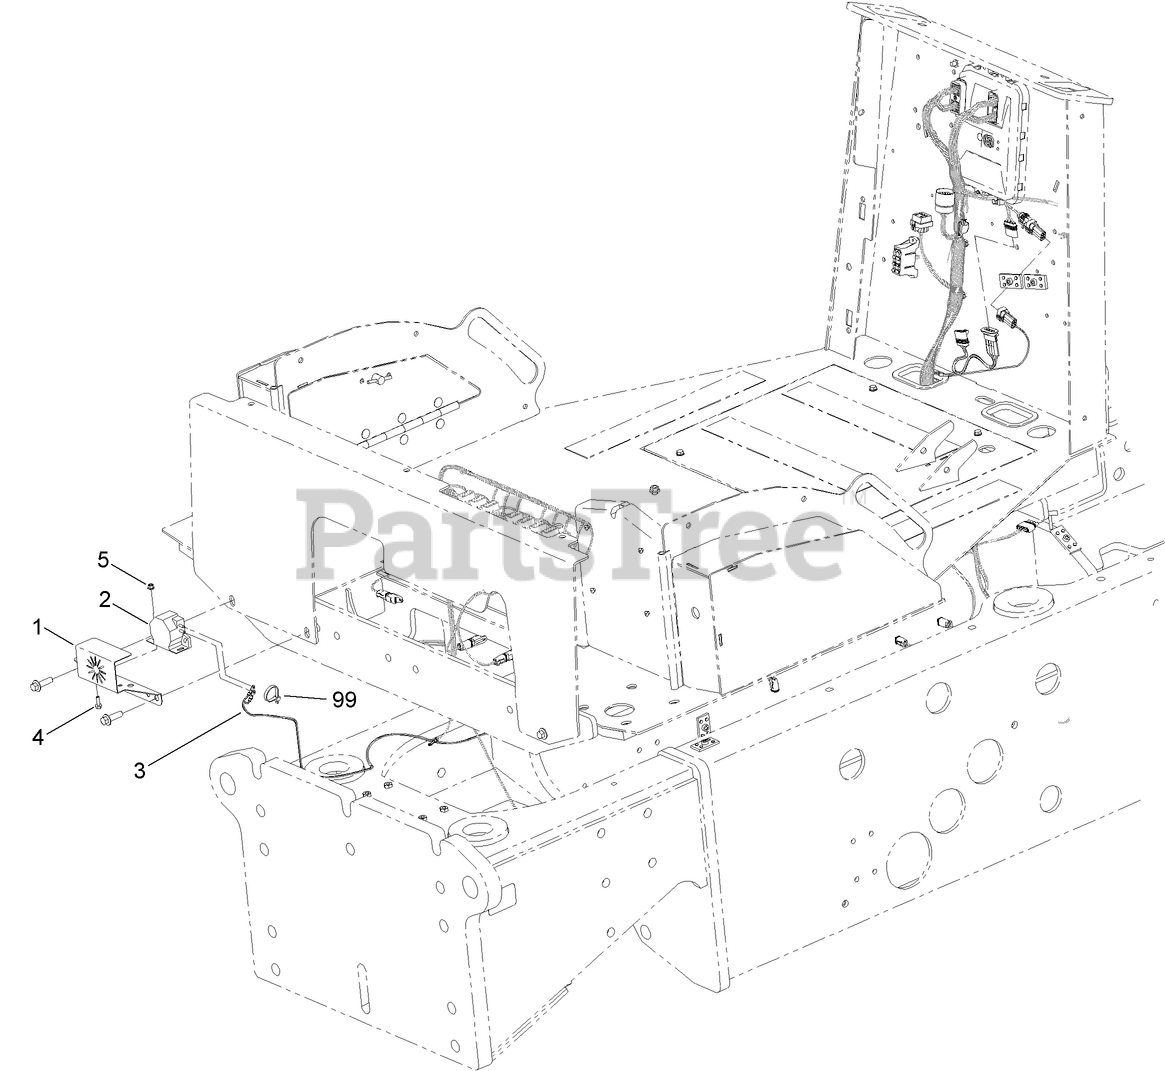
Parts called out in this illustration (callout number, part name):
1	BRACKET-BACKUP ALARM
2	ALARM-BACKUP
3	HARNESS-BACKUP ALARM
4	SCREW-HHF
5	NUT-HHF
99	TIE-CABLE
